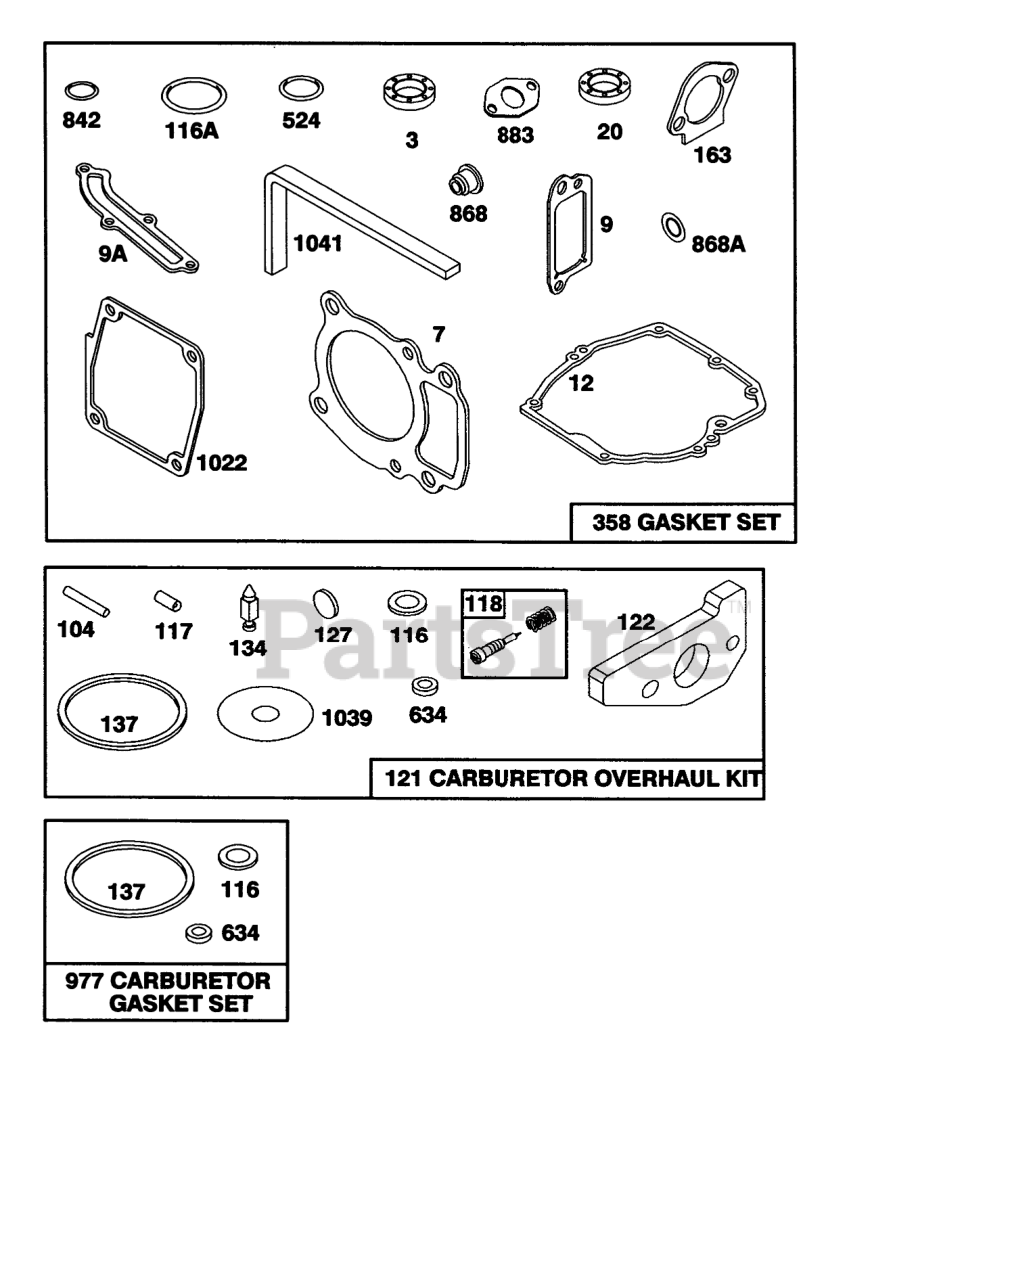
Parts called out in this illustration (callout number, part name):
3	SEAL - OIL
7	CYLINDER HEAD GASKET
9	Gasket-Breather
9A	GASKET-BREATHER
12	ENGINE BASE GASKET
20	SEAL-OIL
104	FLOAT HINGE PIN
116	SEALING GASKET
116A	O RING SEAL
118	VALVE KIT - NEEDLE
121	CARBURATOR OVERHAUL KIT
122	ADAPTER ASSEMBLY
134	Valve-Float (Includes Seat)
137	FLOAT BOWL GASKET
163	AIR CLEANER GASKET
358	GASKET SET
524	O-RING
634	SEAL WASHER
842	O-RING
868	SealAssy-Valve
868A	Seal-Valve
883	EXHAUST GASKET
977	CARBURATOR GASKET SET
1022	ROCKER COVER GASKET
1039	FLOAT LIMITER
1041	SEAL - FOAM
